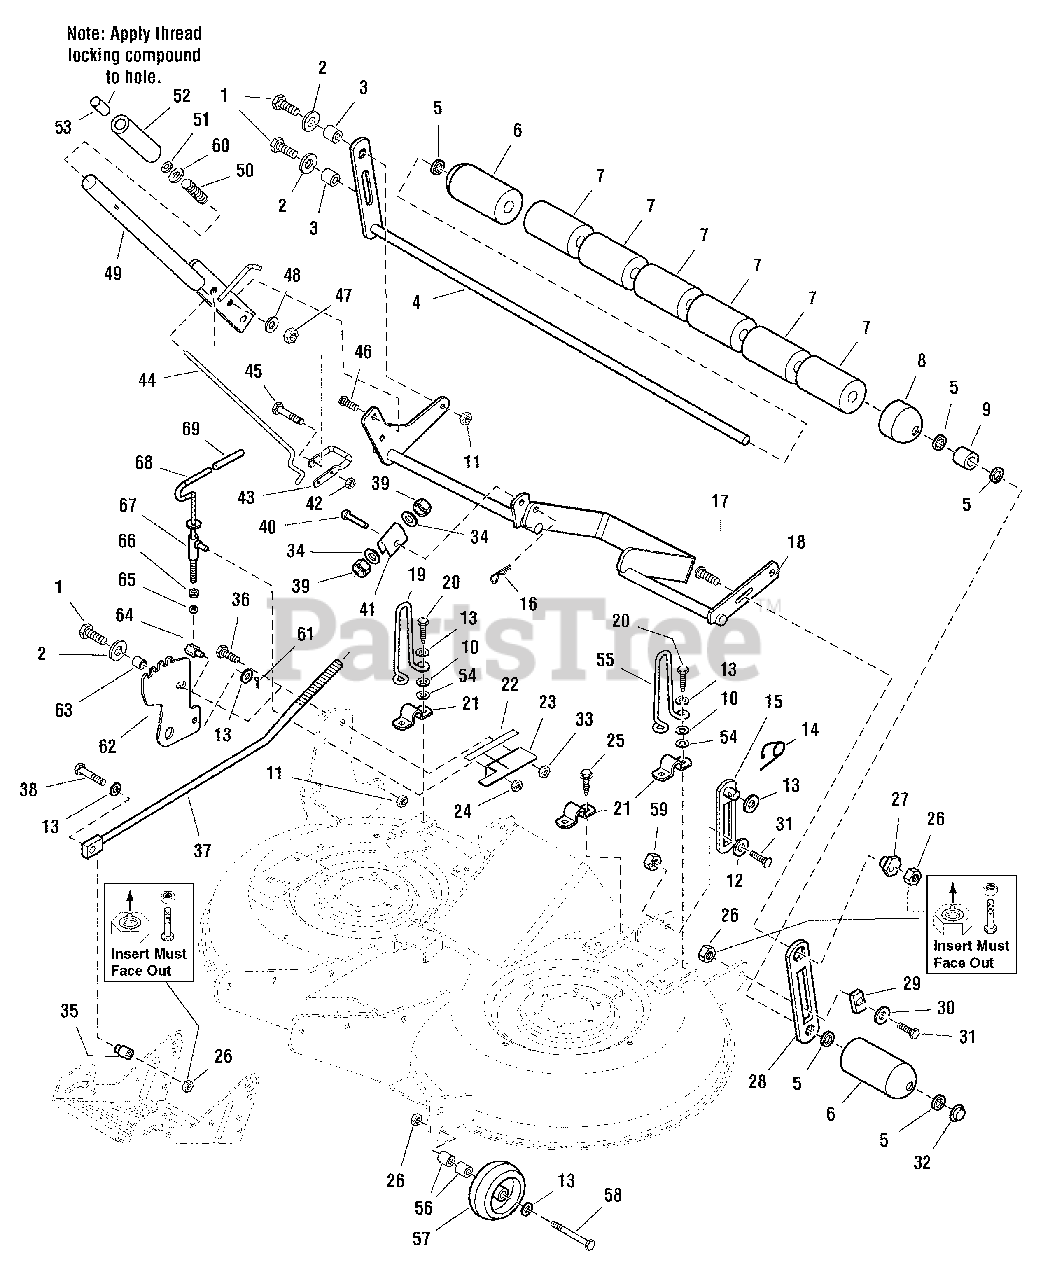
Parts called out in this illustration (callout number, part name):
1	CAPSCREW, Hex Head, 5/16-18 x 1 1/4
4	SHAFT & BAR ASSEMBLY
5	WASHER, 5/8
6	ROLLER, Rounded, 4.1 LG, 650 ID, 2.50 OD Rounded End
7	ROLLER, .652 ID, 2.50 OD, 4.10 LG
8	ROLLER, .650 ID, 2.5" OD, 2.05" Long, Rounded End
9	SPACER, .66 ID
10	WASHER
11	NUT, Hex Flange Lock, 5/16-18
12	WASHER, 3/8
13	WASHER
14	RETAINER, Pin
15	LINK & PIN ASSEMBLY
16	PIN, Retaining
17	BOLT, Carriage, Short Neck, 3/8-16 x 1-1/2
18	SHAFT & ARM ASSEMBLY
20	CAPSCREW, Hex Head Taptite, 5/16-18 x 1-1/4
21	STRAP
22	DECAL, Height of Cut
23	BRACKET, Height of Cut
24	NUT, Hex ESNA, 3/8-16
25	CAPSCREW, Hex Head Taptite, 5/16-18 x 3/4
26	NUT, Hex Flange, 3/8-16
27	NUT, Hex Adjusting, 11/16
30	WASHER
31	BOLT, Shoulder, 3/8-16 X 1.34, 1/2 Shoulder
32	NUT, Push, 5/8
33	NUT, Hex Centerlock, 3/8-16
34	WASHER, 21/32 x 1 x 1/64
36	CAPSCREW, Hex Head, 5/16-18 x 3/4
37	ROD, Adjusting
38	CAPSCREW, Hex Head, 3/8-16 x 1-3/4
39	NUT, Hex, 5/8-11
40	PIN, Round Head Drilled, 3/8 x 2
41	TRUNNION
42	NUT, Hex Lock ESNA, 1/4-20
43	LATCH, "U"
45	CAPSCREW, Hex Head 1/4-20 x 2-1/4
46	BOLT, Carriage, Short Neck, 5/16-18 x 1
47	NUT, Hex, 5/16-18
48	LOCKWASHER, 5/16
49	HANDLE ASSEMBLY, Lift
50	SPRING, Compression
51	NUT, Push
52	GRIP, Black
53	BUTTON, Red
54	NUT, Push
57	WHEEL, Gauge
58	CAPSCREW, Hex Head, 3/8-16 x 3
59	NUT, Hex, 3/8-16
60	WASHER, 11/32 x 11/16 x 1/16
61	PIN, Cotter, 15/16 x 3/4
62	BRACKET, Adjusting
63	SPACER, 21/64 x 1/2 x 7/32
64	PIVOT, 3/4 Hex
65	NUT, Hex Jam, 3/8-16 NC-2B
66	NUT, Hex Flange, 3/8-16
67	GUIDE ASSEMBLY, Rod
68	ROD & WASHER ASSEMBLY, Adjustment Handle
69	GRIP, Black Vinyl
